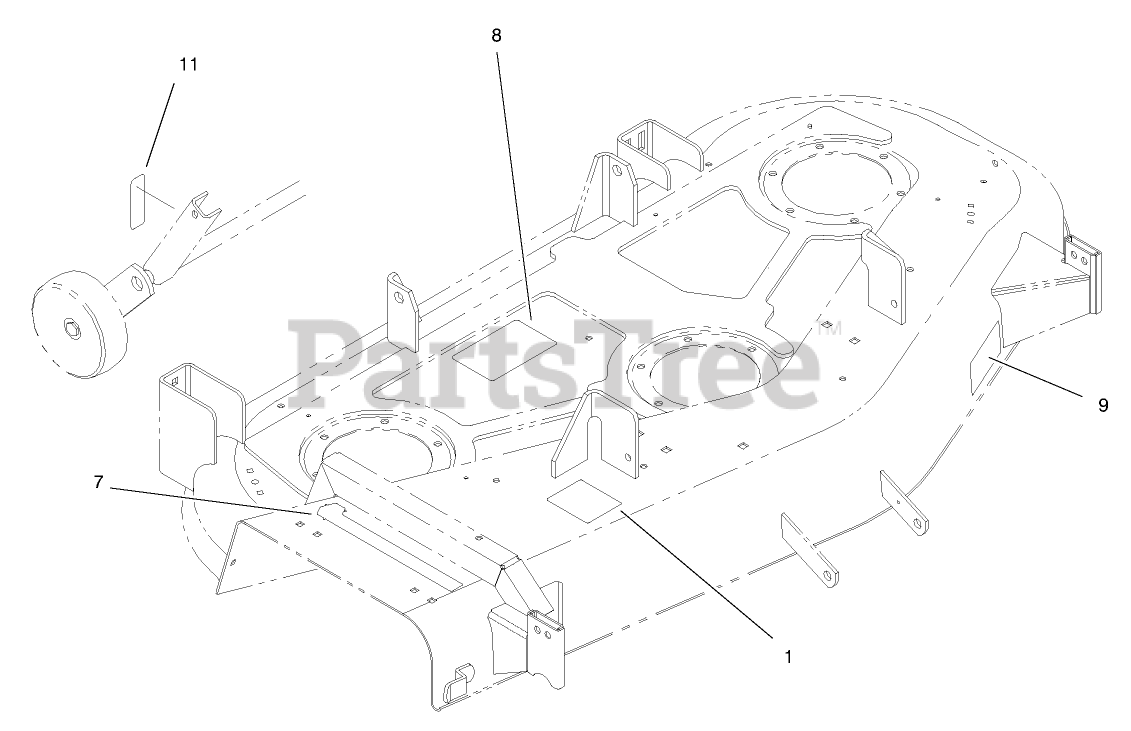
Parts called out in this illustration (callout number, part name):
1	DECAL-BELT ROUTING
7	DECAL-DECK
8	DECAL-BELT ROUTING
9	DECAL-ADJUSTMENT, WHEEL
11	DECAL-HOC
